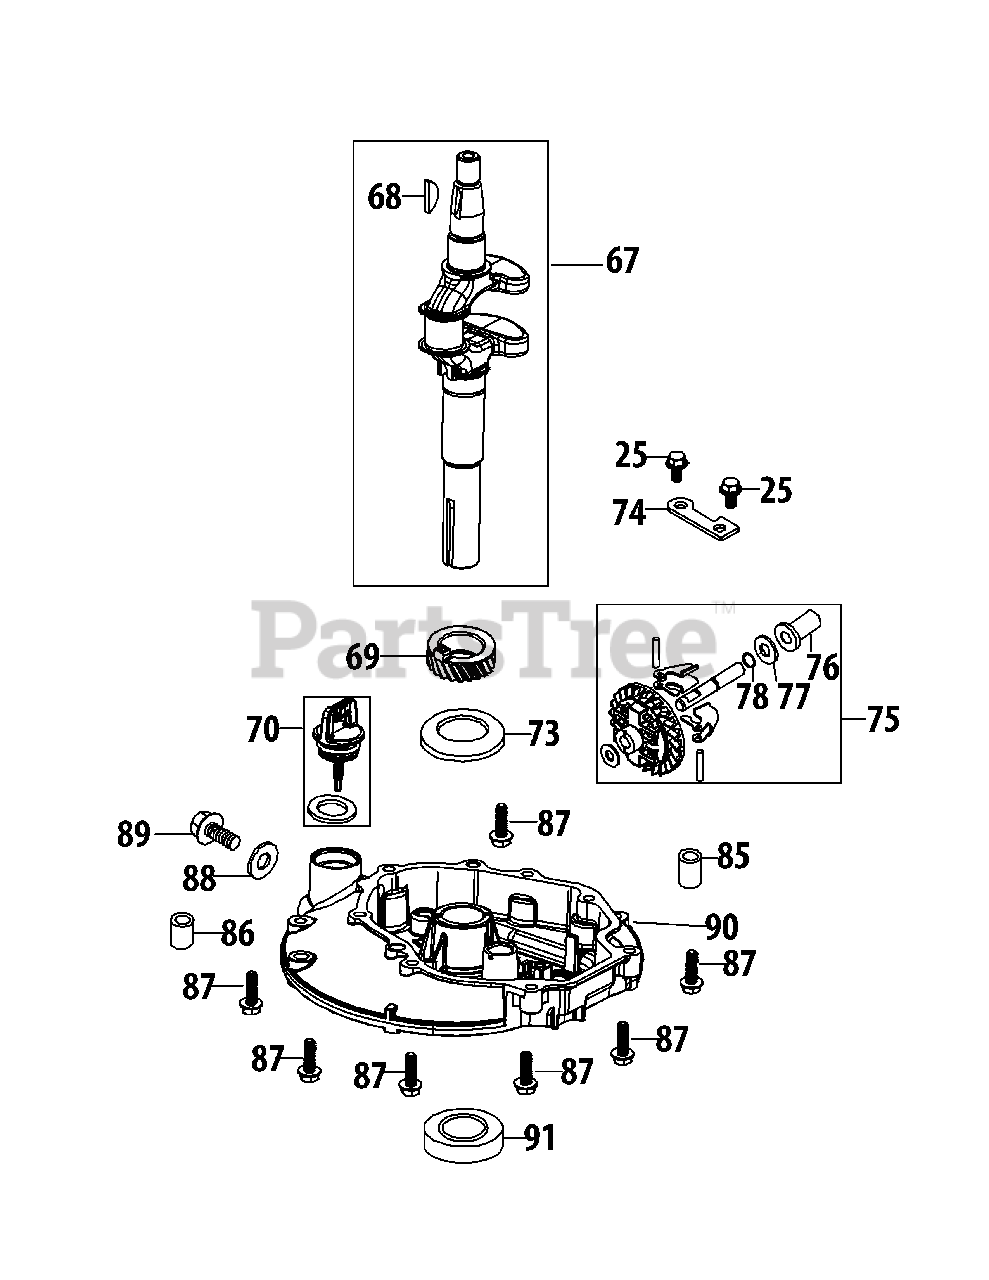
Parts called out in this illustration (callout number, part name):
25.1	Bolt M6X14 Multi-Purpose
67	Crankshaft Assembly
68	Flywheel Key
69	Timing Gear
70	Dipstick Assembly
73	Crankshaft Thrust Washer
74	Governor Gear Mounting Plate
75	Governor Gear/Shaft Assembly
76	Governor Slide Cap
77	Governor Slide Cap Washer
78	Governor Shaft Stop Ring
85	Crankcase Cover Dowel Pin 7×14
86	Crankcase Cover Dowel Pin 9×14
87	Bolt M6X28 T/X/P Crankcase/Dp Stick
88	Oil Drain Plug Washer
89	Oil Drain Plug
90	Crankcase Cover
91	Lower Crankshaft Seal
